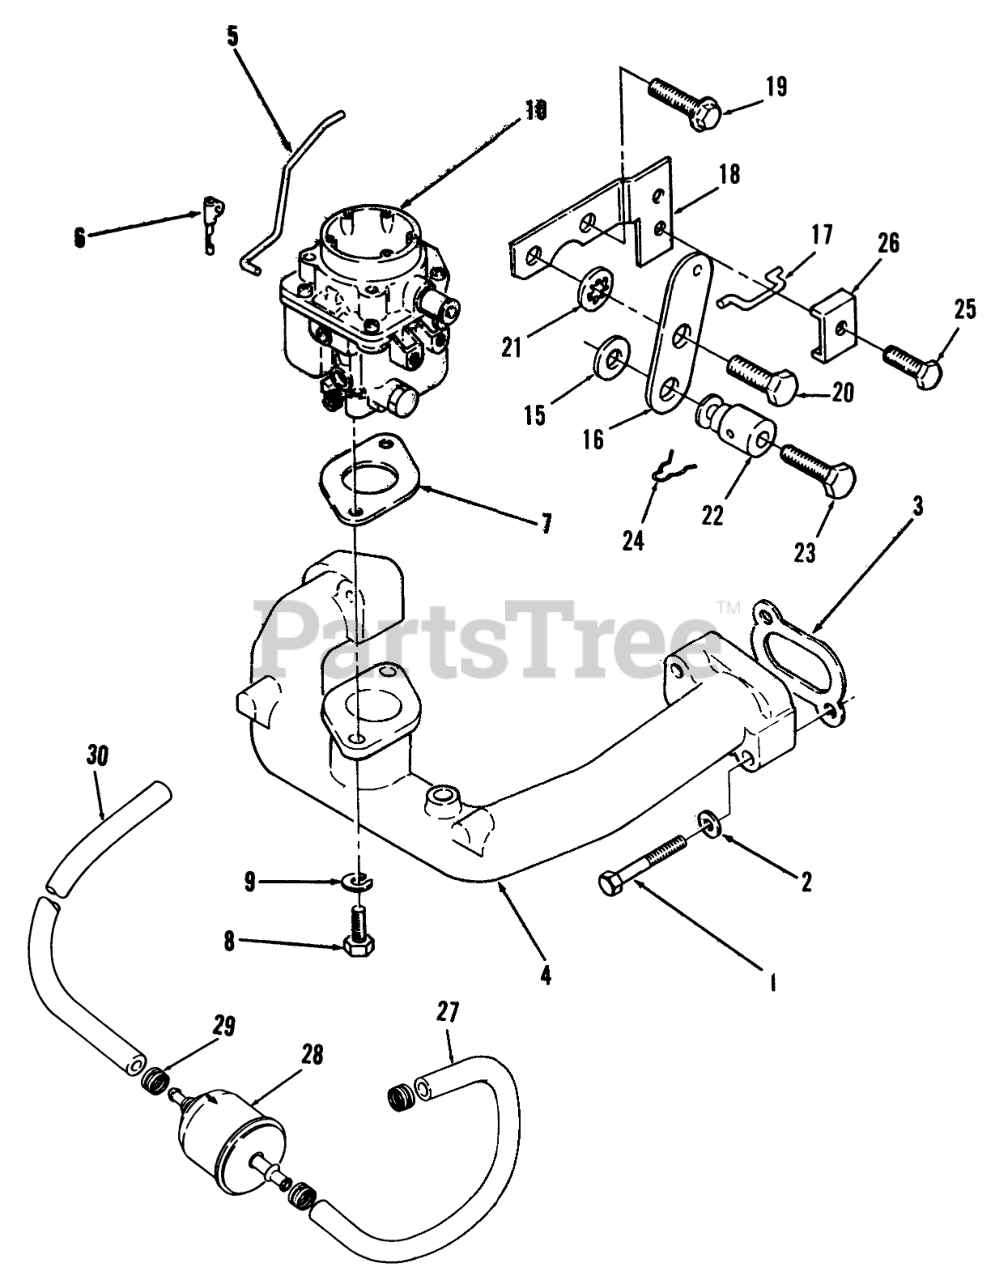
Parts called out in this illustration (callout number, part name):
2	Washer
3	Gasket
4	INTAKE-MANIFOLD
5	GOVERNOR-CONTROL ROD
6	CONTROL-ROD CLIP
7	Gasket
8	HEX-HEAD CAP SCREW
9	Washer
10	COMPLETE-CARBURETOR
15	Washer
16	Lever
17	Link
18	Bracket
19	Bolt
20	Bolt
21	Lockwasher
22	Swivel
23	Bolt
24	Cotler Pin
25	Bolt
26	Clamp
27	Hose
28	Filter-Fuel
29	Clamp
30	Hose
